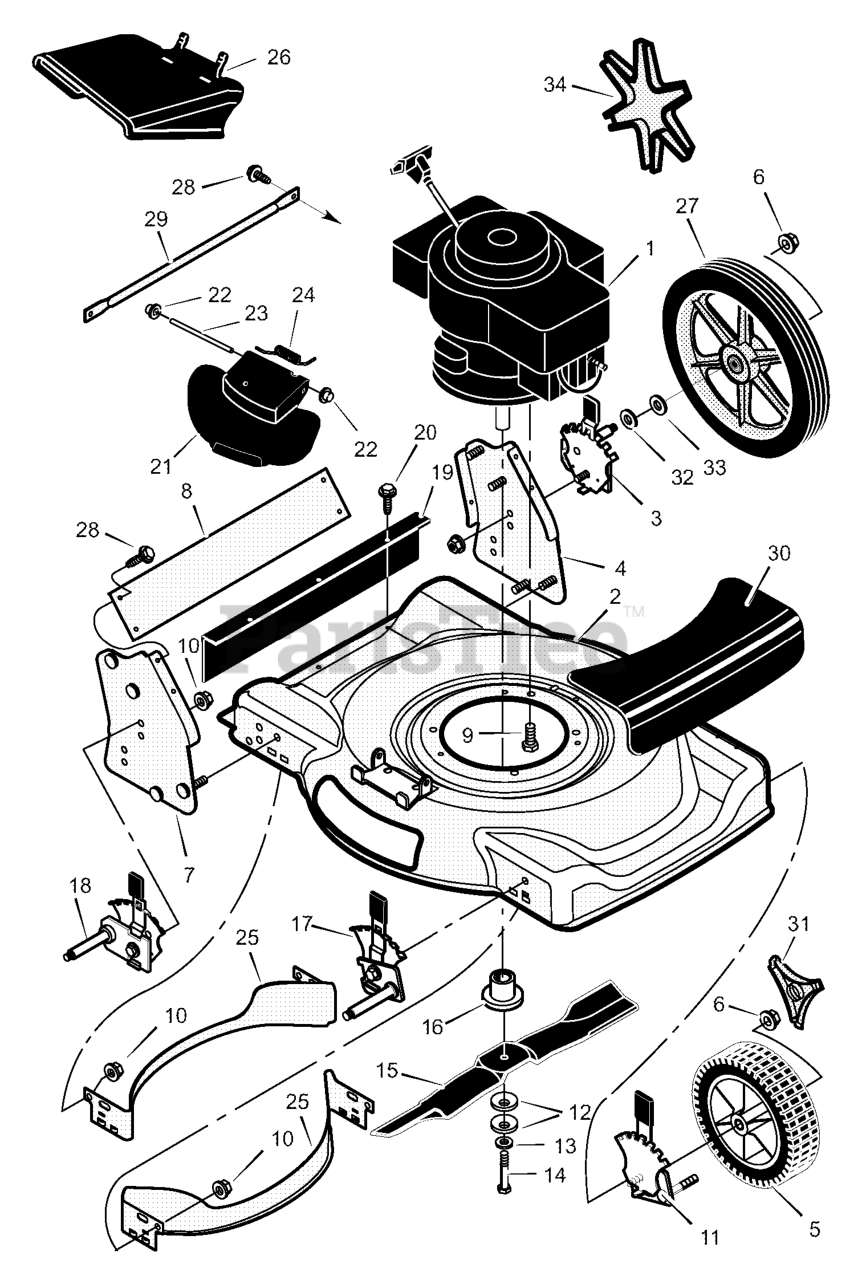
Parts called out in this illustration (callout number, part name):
1	Engine *
2	Housing
3	Height Adjuster, Left Rear
4	Bracket, Left Handle
5	Wheel and Tire, Front
6	Locknut, Flange
7	Bracket, Right Handle
8	Brace, Handle Bracket
9	Bolt, Engine
10	Nut
11	Height Adjuster, Left Front
12	Washer, Belleville
14	Bolt, Hex
16	Adapter, Blade
17	Height Adjuster, Right Front
18	Height Adjuster, Right Rear
19	Guard, Rear
21	Cover, Mulcher
22	Push-On Cap
23	Pin, Pivot
26	Deflector, Chute
27	Wheel and Tire, Rear
30	Cover, Front
31	Cap, Hub
34	Cap, Hub
